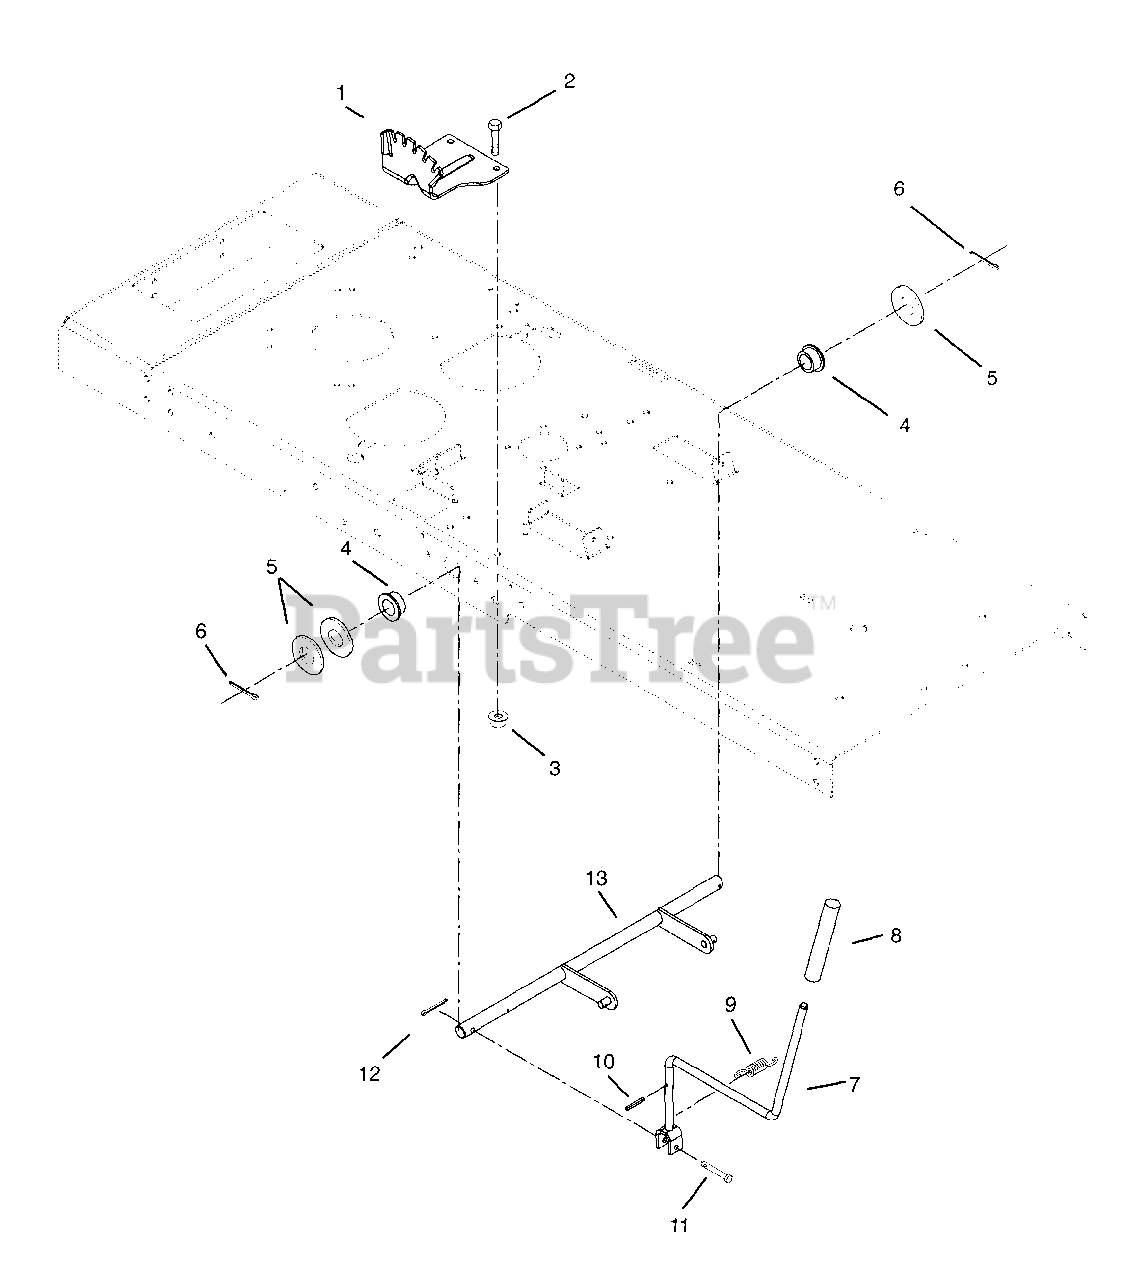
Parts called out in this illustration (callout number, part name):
1	DETENT PLATE
2	@BLT-HEX .38-16X1.00 GR5 YWZC
3	@NUT-LK-CTR .38-16 YWZC
4	BSHG-FLG1.020X1.385X.75X1.75NY
5	WSHR-FL-STL 1.062X2.000X.134
6	@PIN-CTR .18X1.50 EXTPRSQCT YZ
7	LIFT LEVER WELDMENT
9	SG-TENS .120X1.0X4.46 WLD 47
10	PIN-ROLL .250X1.00
11	PIN-CLEV .370X1.75
12	@PIN-CTR .12X1.00 EXTPRSQCT YZ
13	LIFT SHAFT WELDMENT
